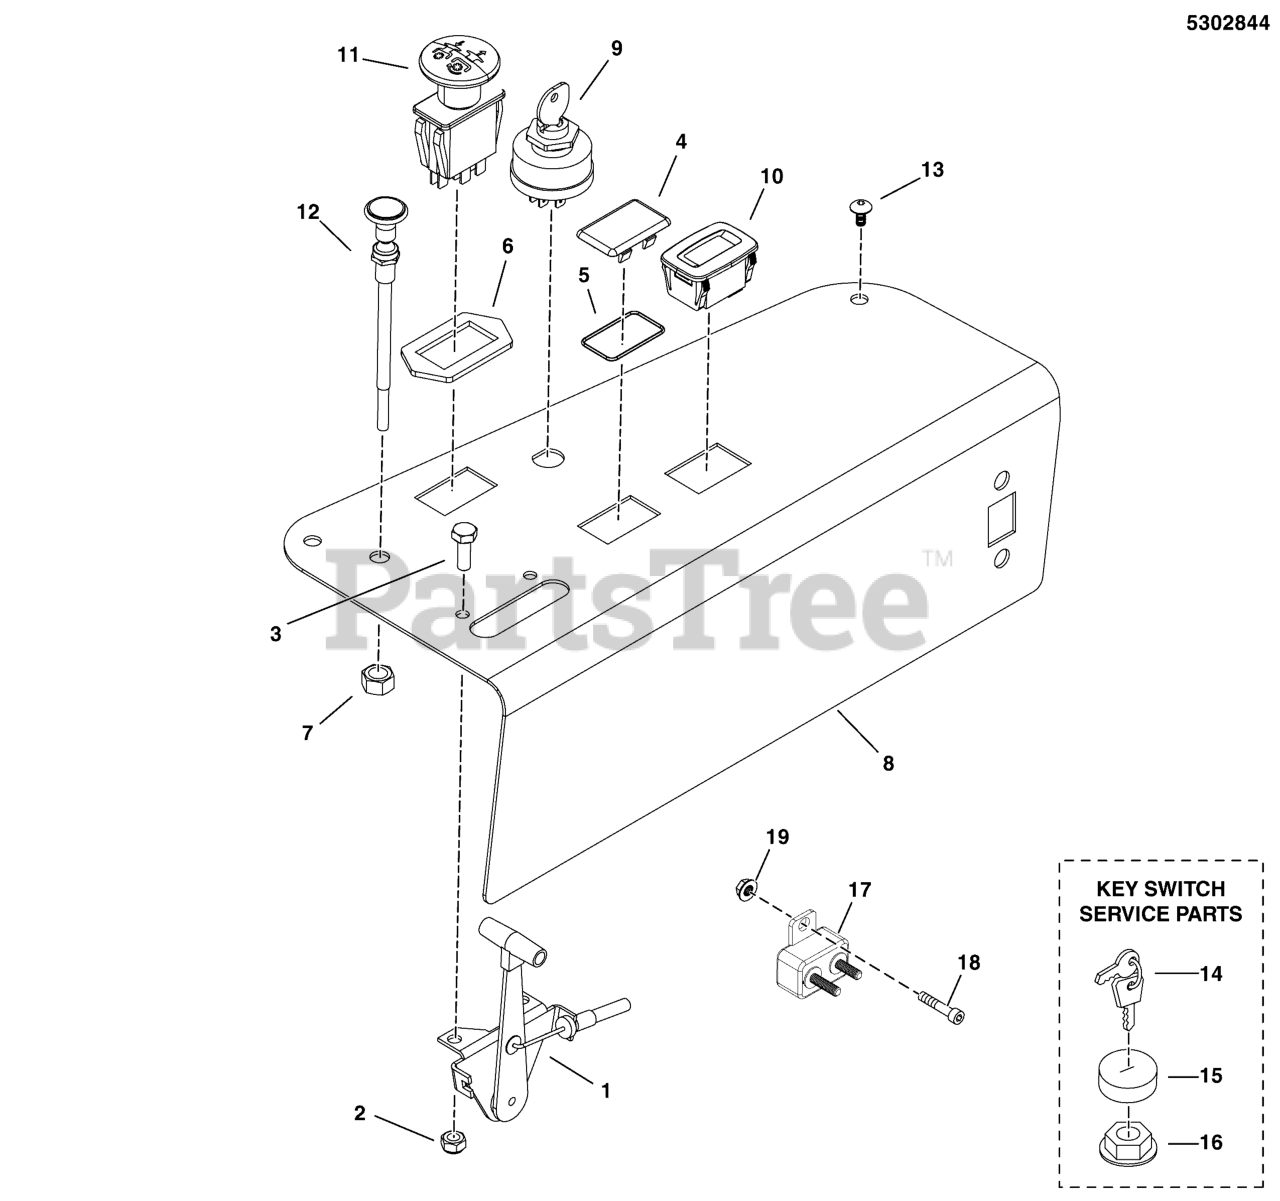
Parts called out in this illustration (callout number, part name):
1	CABLE, THROTTLE CONTROL, 38
2	NUT, 1/4-20 HEX NYLON LOCK
3	BOLT, 1/4-20 X 3/4 GD5 YZ
4	PLUG, .820X1.44 HOLE, BLACK PLASTIC
5	O-RING, 7/8 ID X 1/16 W
6	RING, SWITCH RETAINER
7	NUT, 3/8-24 HEX
8	PLATE, CONTROL PANEL - BLACK
9	SWITCH, IGNITION, 6 POST
10	HOUR METER
11	SWITCH, BLADE ENGAGEMENT
12	CABLE, CHOKE CONTROL, 47
13	SCREW, ALLEN HEAD 1/4-20X.500 ZINC PHOS
14	KEY, IGNITION MOLDED SET
15	COVER, PLASTIC, SNAP ON
16	PLASTIC NUT
17	BREAKER-CIRCUIT 12VOLT 20AMPS W/TAB
18	SCREW, ALLEN HEAD 1/4-20X.500 ZINC PHOS
19	NUT, 1/4-20 HEX SERR. FLANGE
